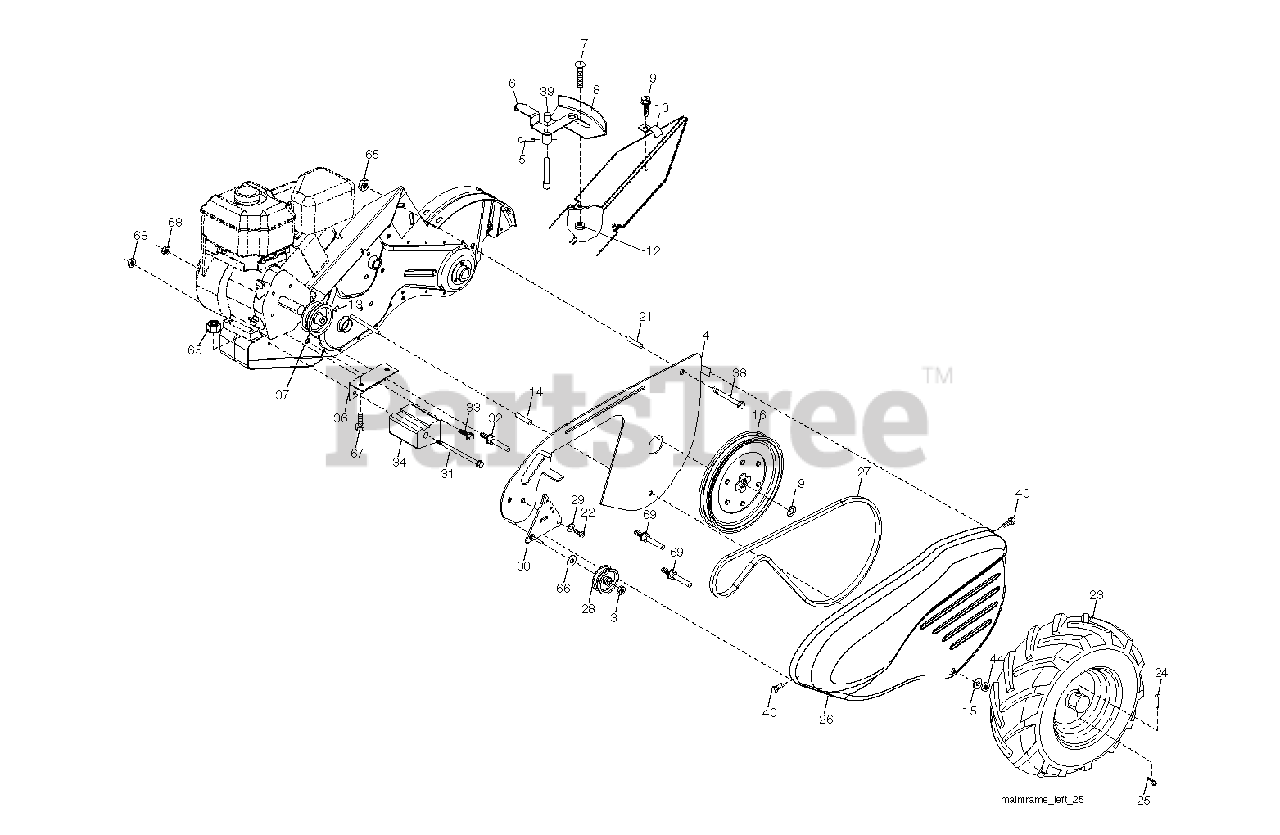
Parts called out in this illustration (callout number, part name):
3	NUT.HEX.3/8-16UNC
4	SHIELD.INNER.BELT.GUARD.RT
5	PIN.SPIROL.FLARED
6	LEVER ASM CRT
9	TAPPING SCREW
10	CONDUIT CLIP T
12	NUT
13	SET SCREW **
14	SPACER-SPLIT.327 X .42
15	WASHER
16	SHEAVE, TRANSMISSION
19	RETAINING RING LT
21	SPACER CRT
23	RIM
23	VALVE STEM LT
24	RIVET,DRILLED
25	RETAINER M
27	V-BELT
28	PULLEY-IDLER TI
29	KLIP RING
30	BRACKET.ASM.IDLER
31	BOLT.FIN.HEX.3/8-16UNC
32	SHIFT ARM CRT
33	BOLT
34	COUNTERWEIGHT.LH.CRT
36	BRACKET LH CRT
37	ENGINE PULLEY
38	BOLT
39	CAP.PLUNGER.BLACK
40	SCREW.HEX.WSH.SLT.#10-24X.50
44	NUT.71038.31-18.HEX.NYLOCK
65	LOCKNUT-FLANGE 5/16-18
66	WASHER
67	BOLT, HEX 5/16-18X1-3/4
69	KEEPER.BELT.ENGINE
